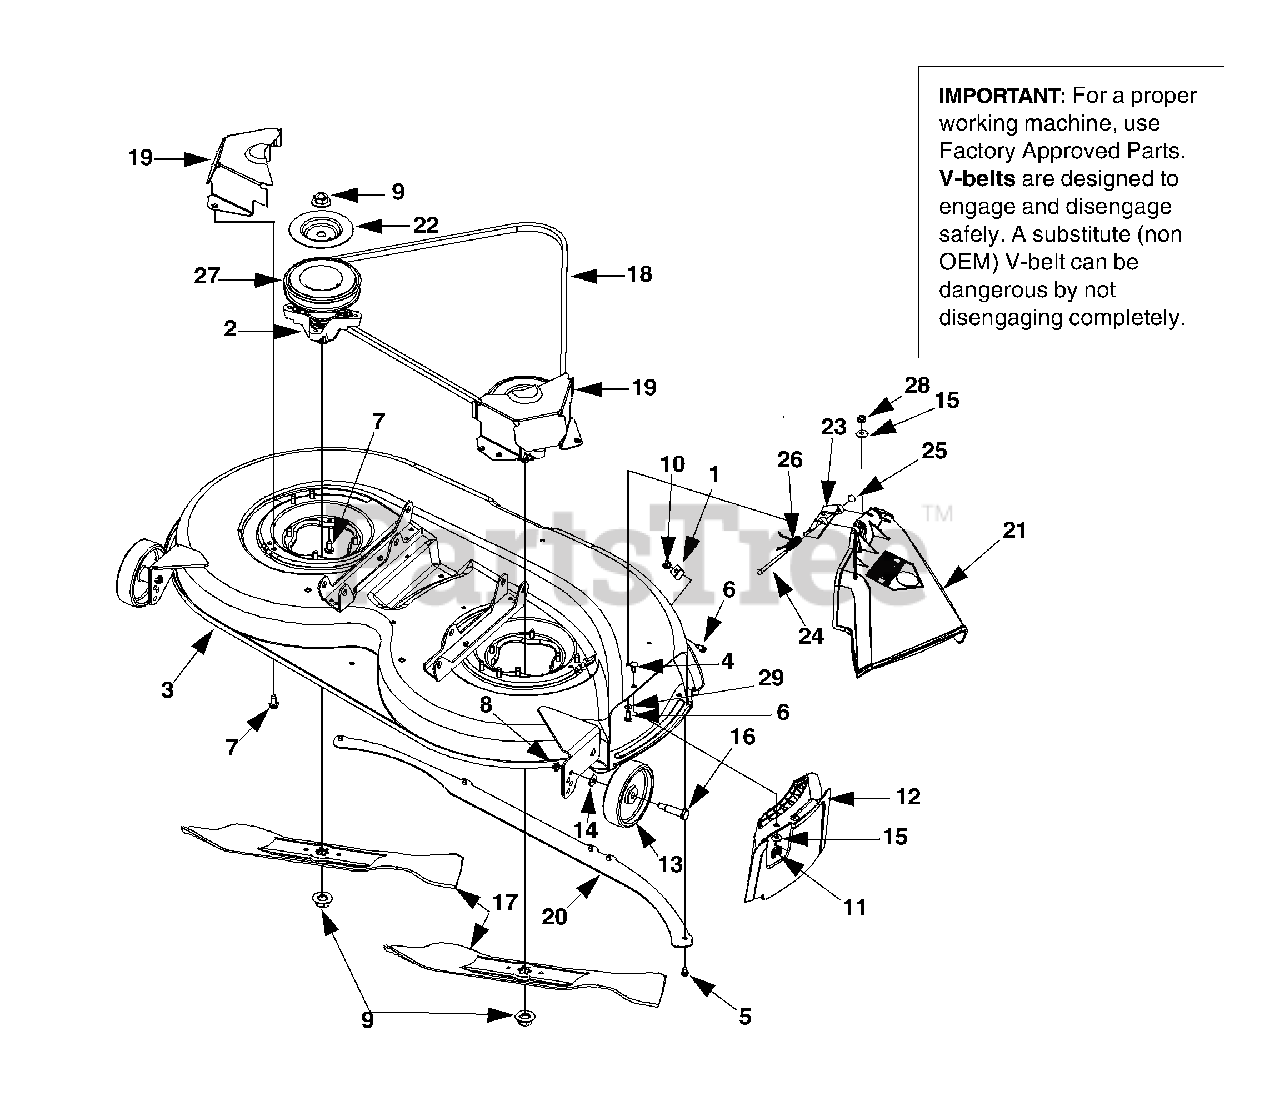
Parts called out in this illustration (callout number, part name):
1	Retainer Hook Brkt.
2	Blade Spindle Ass'y
5	Hex Wash. Hd. TT-Tap Screw 1/4-20 Thd.
6	Hex Bolt 1/4-20 x .62"
7	Hex Wash. TT-Tap Scr. 5/16-18 x .75"
8	Jam Nut 3/8-16
9	Hex Flange Nut 5/8-18 Thd.
10	Hex Flange Nut 1/4-20 Thd.
11	WIng Nut 1/4-20
12	Mulch Plug
13	Deck Wheel-5"
14	Bell-Wash. .40" I.D. x .88" O.D.
15	Bell-Wash. 1/4 I.D.
16	Shoulder Screw
17	3 in 1 blade
18	V Belt
21	Chute Ass'y
22	Brake Disc.
23	Hinge Mounting Brkt.
24	Hinge Pin
25	Speed Nut Cap
26	Torsion Spring
27	5.75" Dia. Pulley
28	Hex Nut 1/4-20 Gr. 5
